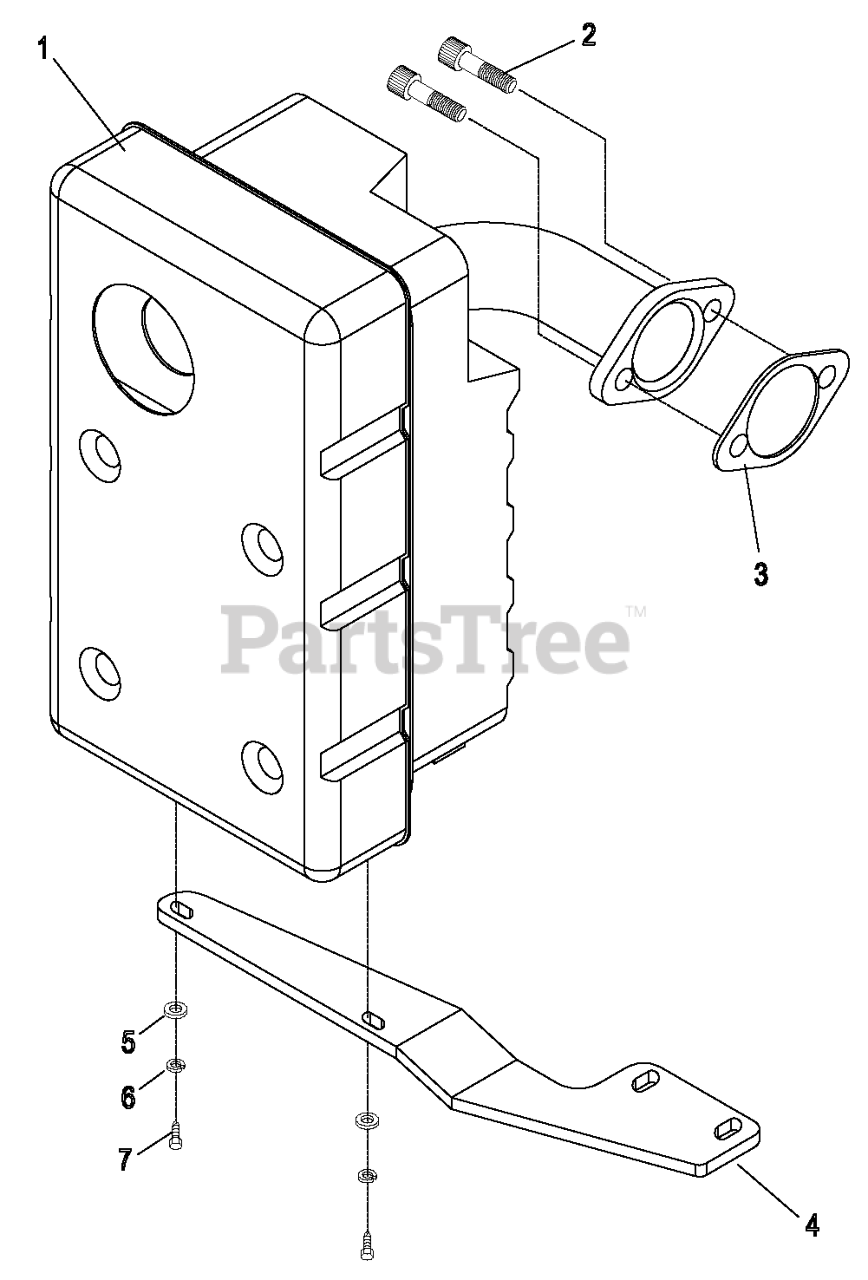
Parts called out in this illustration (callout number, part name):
1	MUFFLER, 410 SIDE-OUT ALUMINIZED
2	SCREW SHC M8-1.25 X 20 SEMS
3	GASKET, EXHAUST
4	BRACKET, GH410 MUFFLER SUPPORT
5	WASHER FLAT 1/4 - M6 ZINC
6	WASHER LOCK M6 - 1/4
7	SCREW HHC M6-1.0 X 10 G8.8
